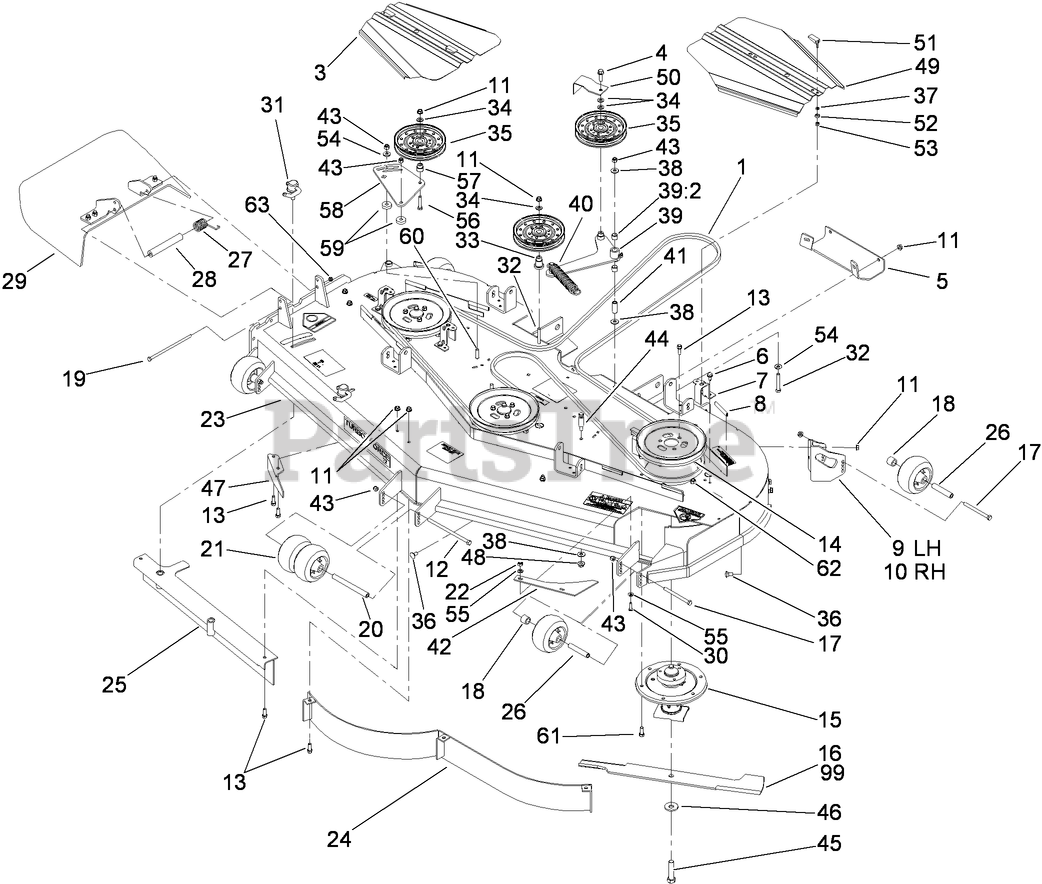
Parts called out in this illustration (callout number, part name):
3	COVER-BELT, RH
4	SCREW-HHF
5	Plate-Skid
6	SCREW-HWHTF
7	BRACKET-COVER
8	STRIP-SEAL
9	MOUNT-WHEEL, LH
10	MOUNT-WHEEL, RH
11	NUT-HHF, WHIZ
12	SCREW-HH
13	SCREW-HWH
14	Pulley
15	SPINDLE ASM
16	BLADE-HI FLOW, 24.5 INCH
17	SCREW-HH
18	TUBE-SPACER
19	SCREW-HH
20	SPACER-WHEEL
21	ROLLER-SCALP, ANTI
22	NUT-LOCK, NI
23	DECK DECAL ASM
26	TUBE-SPANNER
27	SPRING-TORSION
28	SPACER
29	RUBBER DEFLECTOR ASM
30	SCREW-HSBH
31	LEVER ASM
32	SCREW-HH
33	MOUNT-PULLEY
34	WASHER-FLAT
35	Idler-Flat
36	SCREW-CARR
37	WASHER
38	WASHER-FLAT
39	DECK IDLER ARM ASM
39:2	SLEEVE-BEARING
40	SPRING-EXTENSION
41	BUSHING
42	PLATE-TURBO
43	NUT-LOCK, NI
44	PIN-THREADED, SPRING ANCHOR
45	Screw-Cap
46	Washer-Blade Bolt, Heavy
47	BAFFLE-DISCHARGE
48	NUT-HF
49	COVER-BELT, LH
50	GUIDE-BELT
51	HANDLE-LATCH, SWELL
52	BUSHING-LATCH, SWELL
53	NUT-LOCK, HH
54	WASHER-BELLEVILLE
55	WASHER-SPRING
56	SCREW-HH
57	BUSHING-IDLER
58	Plate-Idler
59	Spacer
60	SCREW-CARR
61	SCREW-HH
62	NUT-LOCK, NI
63	NUT-LOCK, NI
99	BLADE-MID FLOW, 24.5IN
99	BLADE-RECYCLER, 24.5IN
99	BLADE-ATOMIC, 24.5IN
99	BLADE-LO FLOW, 24.5IN
